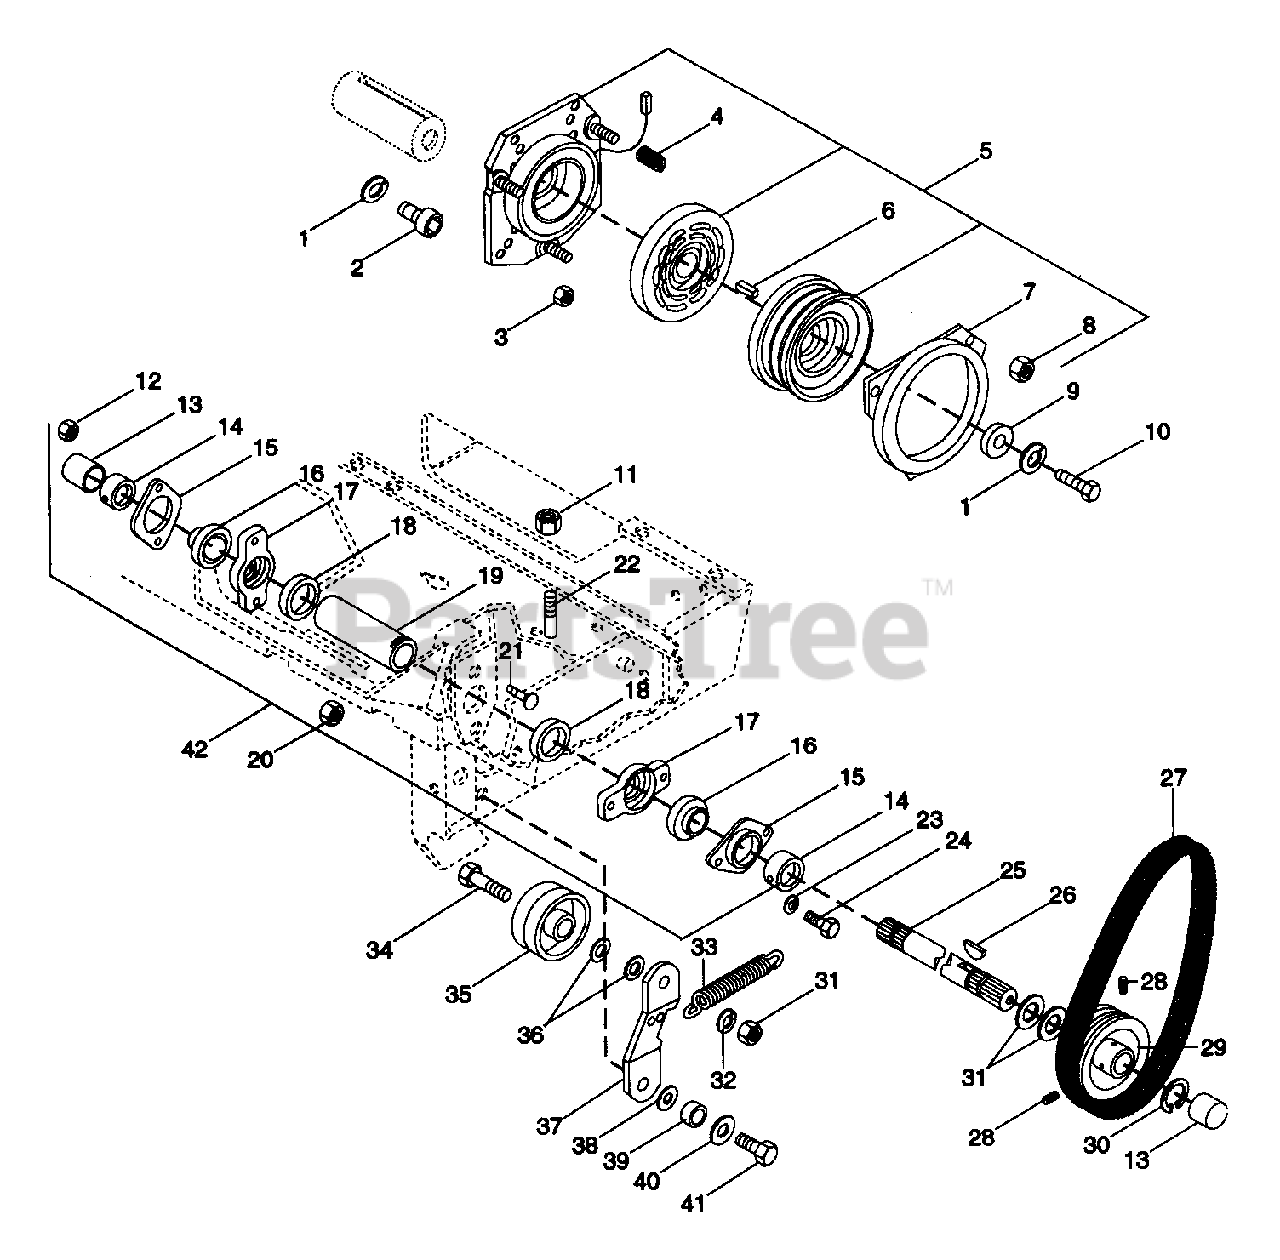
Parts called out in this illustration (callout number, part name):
1	WSHR-LK .438X.133 HVY
2	SCR-SKH .44-14X.75 GR 2 PL
3	NUT-LK-CTR .375-16 GR A PL
4	SG-COMP WARNER ELEC.
5	CLUTCH ASSEMBLY 1 1/8 BORE
6	KEY-SQ .25X.625X.25 SAE 8630
7	BRAKE DRUM
8	NUT-LK WARNER
9	WSHR-FL-STL .515X1.625X.250
10	BLT-HEX .44-20X1.50 PL GR5
11	NUT-LK-JAM-CTR .375-16 PL
12	NUT-LK-CTR .375-16 GR A PL
13	SHAFT COVER
14	BEARING COLLAR
16	BRG/W COLLAR 1.0 X 2.047 X.844
17	BRG FLANGE
18	BSHG-SLV 1.500X1.750X.560
19	PTO TUBE
20	NUT-LK-CTR .50-13
21	BLT-RDHDSQNK .38-16X1.50 PL
22	LOCK STUD
23	WSHR-LK .375X.094 MED PL
24	BLT-HEX .38-16X1.50 PL GR2
25	FRONT PTO SHAFT
26	KEY-FTHR .25X1.25X.25 SAE
27	V-BELT, 4L-WRAPPED (SET)
28	SCR-SET .32-18X.38 SKHCUPNL OH
30	RG-RTNG-EXT 1.00X.042
31	WSHR-FL-STL 1.010X1.505X.062PL
32	NUT-HEX .375-16
33	SPRING ASSEMBLY
34	BLT-HEX .38-16X2.00 PL GR2
35	IDLER-FLAT 3.25 X .38 NWHAMSHR
36	WSHR-FL-STL .38X.875X.083 PL
37	IDLER ARM
38	SHIM SPACER
39	SPACER .512X.747X.208
40	WSHR-FL-STL .518X2.000X.105
41	BLT-HEX .50-13X1.25 PL GR2
42	FRONT PTO KIT
